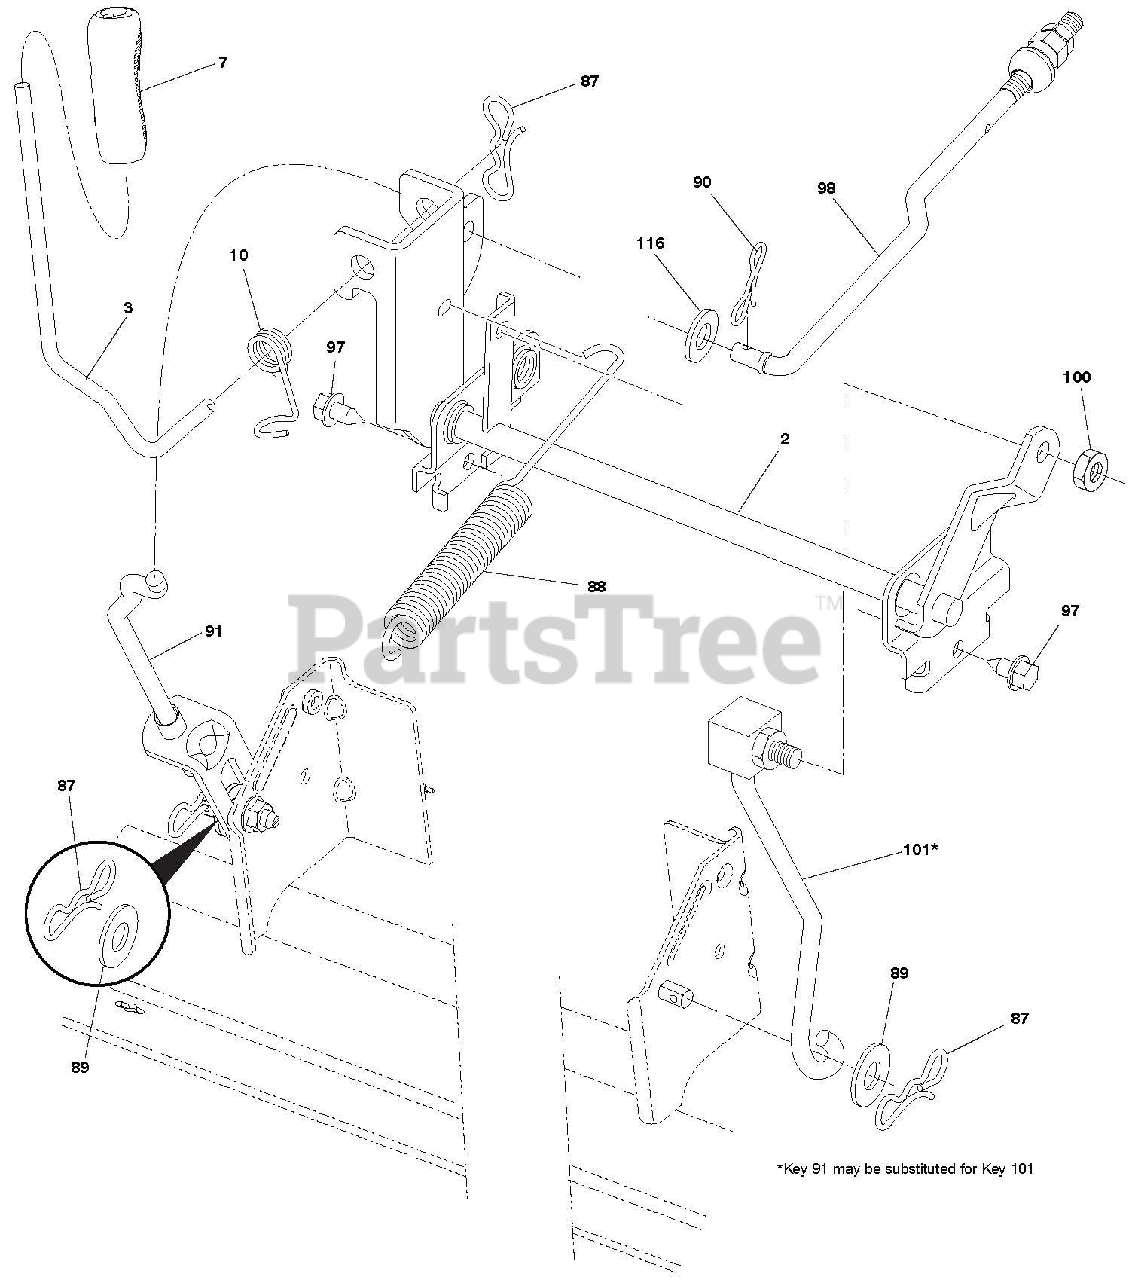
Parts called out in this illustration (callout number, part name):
2	SHAFT ASM., LIFT
3	LEVER.LIFT.HANDLE.LT
7	GRIP LEVER 5625 LD BLACK 428
10	SPRING.TORSION.HANDLE.LIFT
87	PIN.COTTER.7/16.BOW TIE LOCK
88	SPRING.LIFT ASSIST
89	WASHER.CLEAR ZINC
90	PIN.COTTER.5/16.BOW TIE LOCK
91	LINK ASM.LIFT.LH.REAR
97	SCREW.HEXWSH THDR3/8-16X3/4.BL
98	LINK ASM.SUSP.FRONT.MWR.11
100	NUT.CENTERLOCK.3/8-16 UNC.
101	LINK ASM.LIFT.FIXED.38/42/46"
116	WASHER 15/32 X 15/16 X 16 GA.
